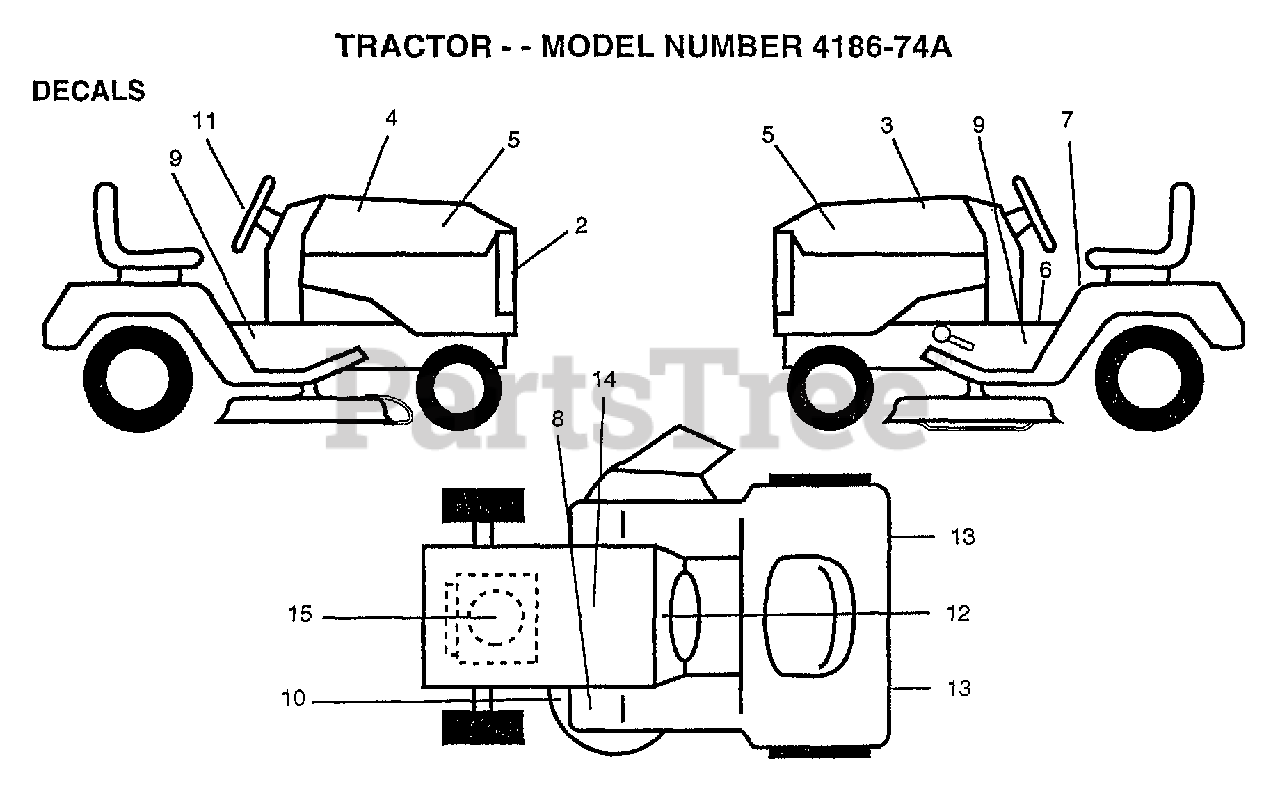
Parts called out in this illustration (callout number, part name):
2	GRILL DECAL
3	HOOD DECAL LH
5	NAMEPLATE LOGO
6	DECAL BRAK PARK
7	"DECAL DANGER,FEND"
9	DECAL CHASSIS
10	"DECAL.V.BELT.44"""
12	"DECAL-OPER,GEAR D"
13	REFLECTOR-TAIL YT
14	DECAL.BATRY.3-3908
15	DECAL, HP ENGINE
